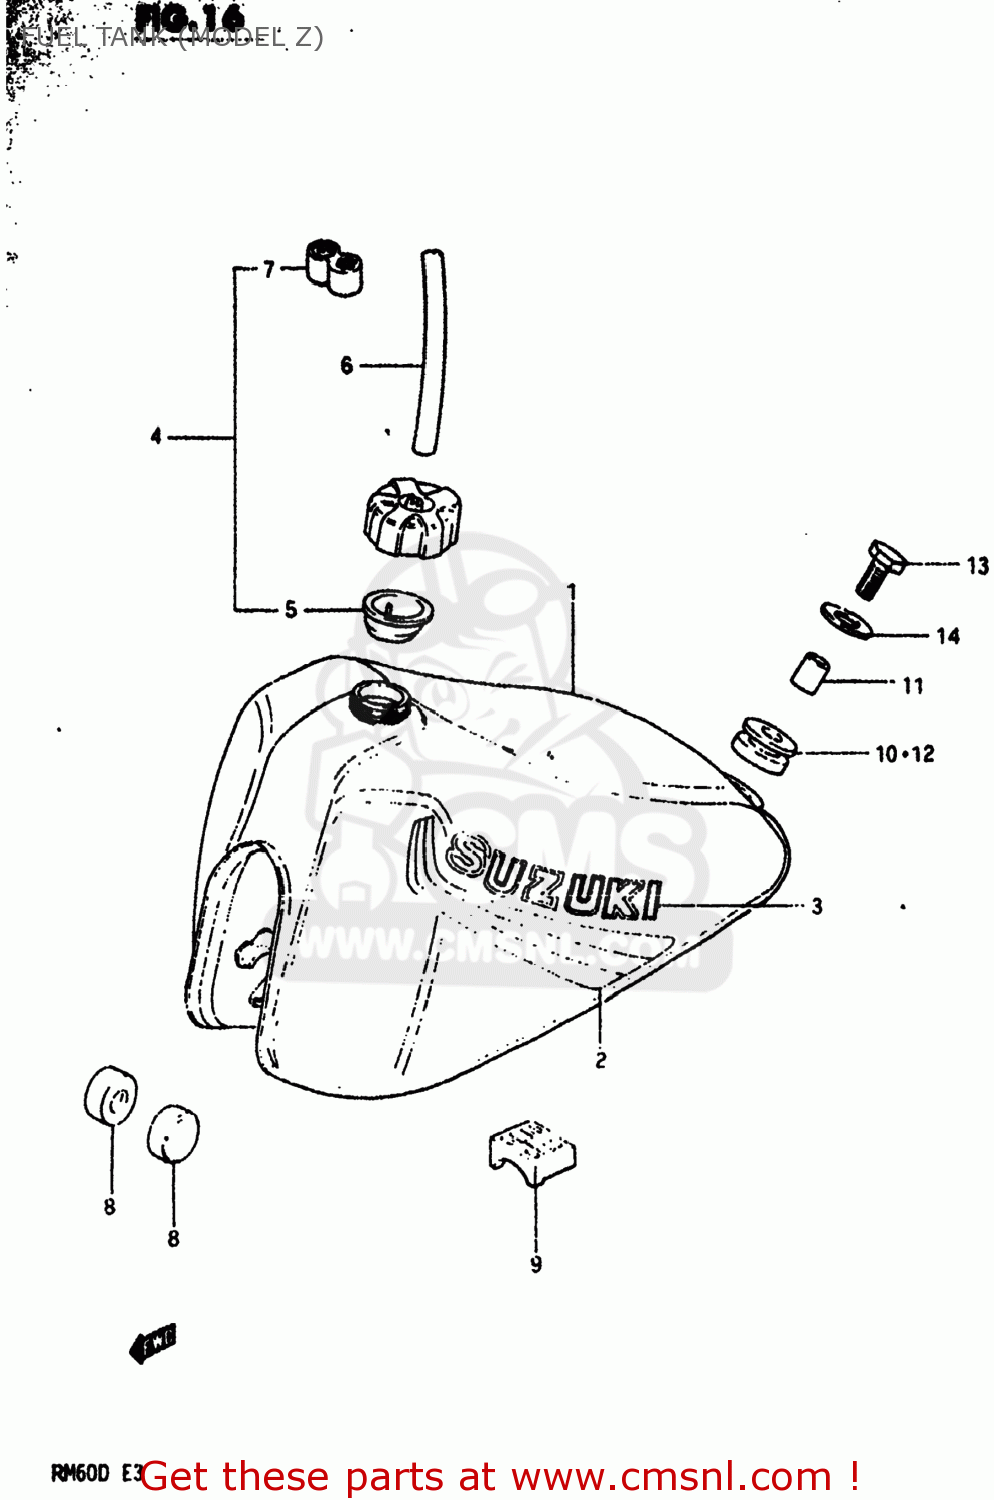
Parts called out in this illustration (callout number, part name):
1	TANK ASSEMBLY,FUEL
2	TAPE SET,FUEL TANK
3	EMBLEM
4	CAP ASSEMBLY,FUEL TANK
5	GASKET,FUEL TANK CAP
6	HOSE
7	CLAMP,FUEL TANK BREATHER HOSE
8	CUSHION
9	CUSHION,FUEL TANK
10	CUSHION
11	SPACER (8.8X12X13.5)
12	CUSHION
13	BOLT
14	WASHER (8.5X29X1.6)
